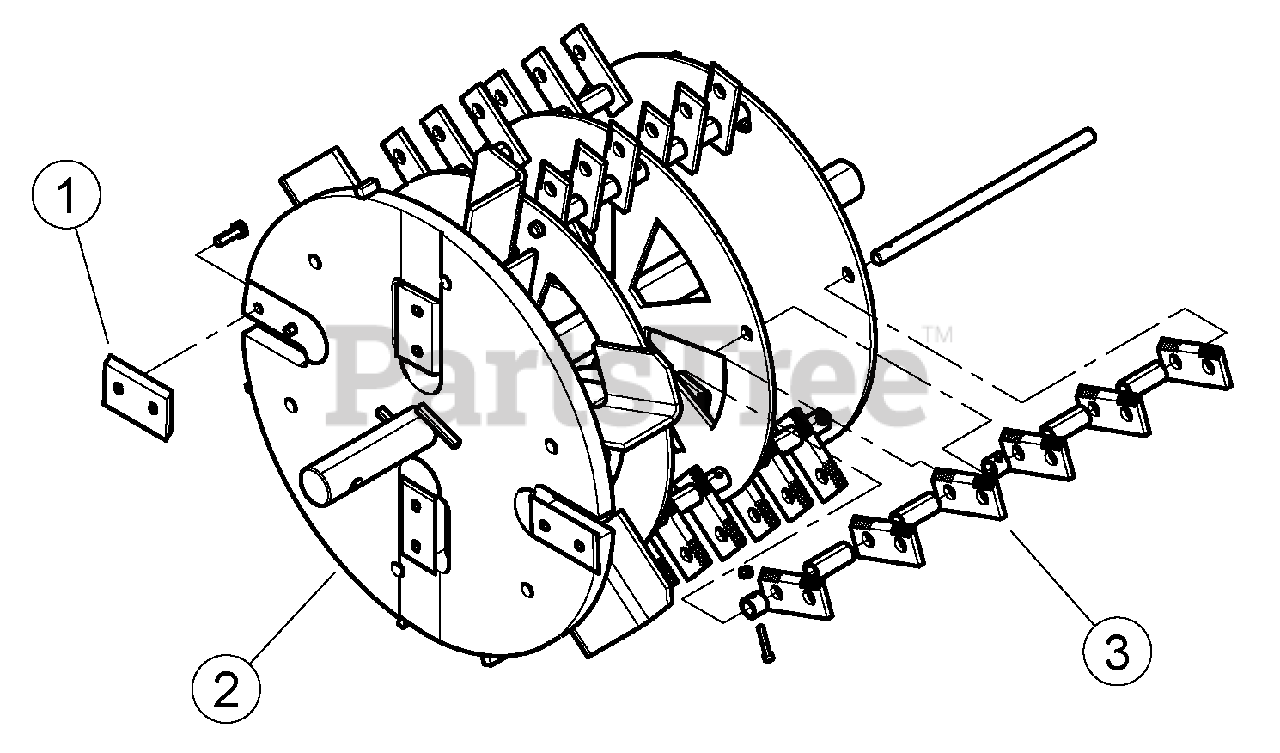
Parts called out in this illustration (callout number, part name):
1	KIT, CHIPPER BLADE
2	WELDMENT, 5 INCH C/S ROTOR
3	SHREDDER KNIVES
3	KIT, SC5720B SHREDDER KNIVES
